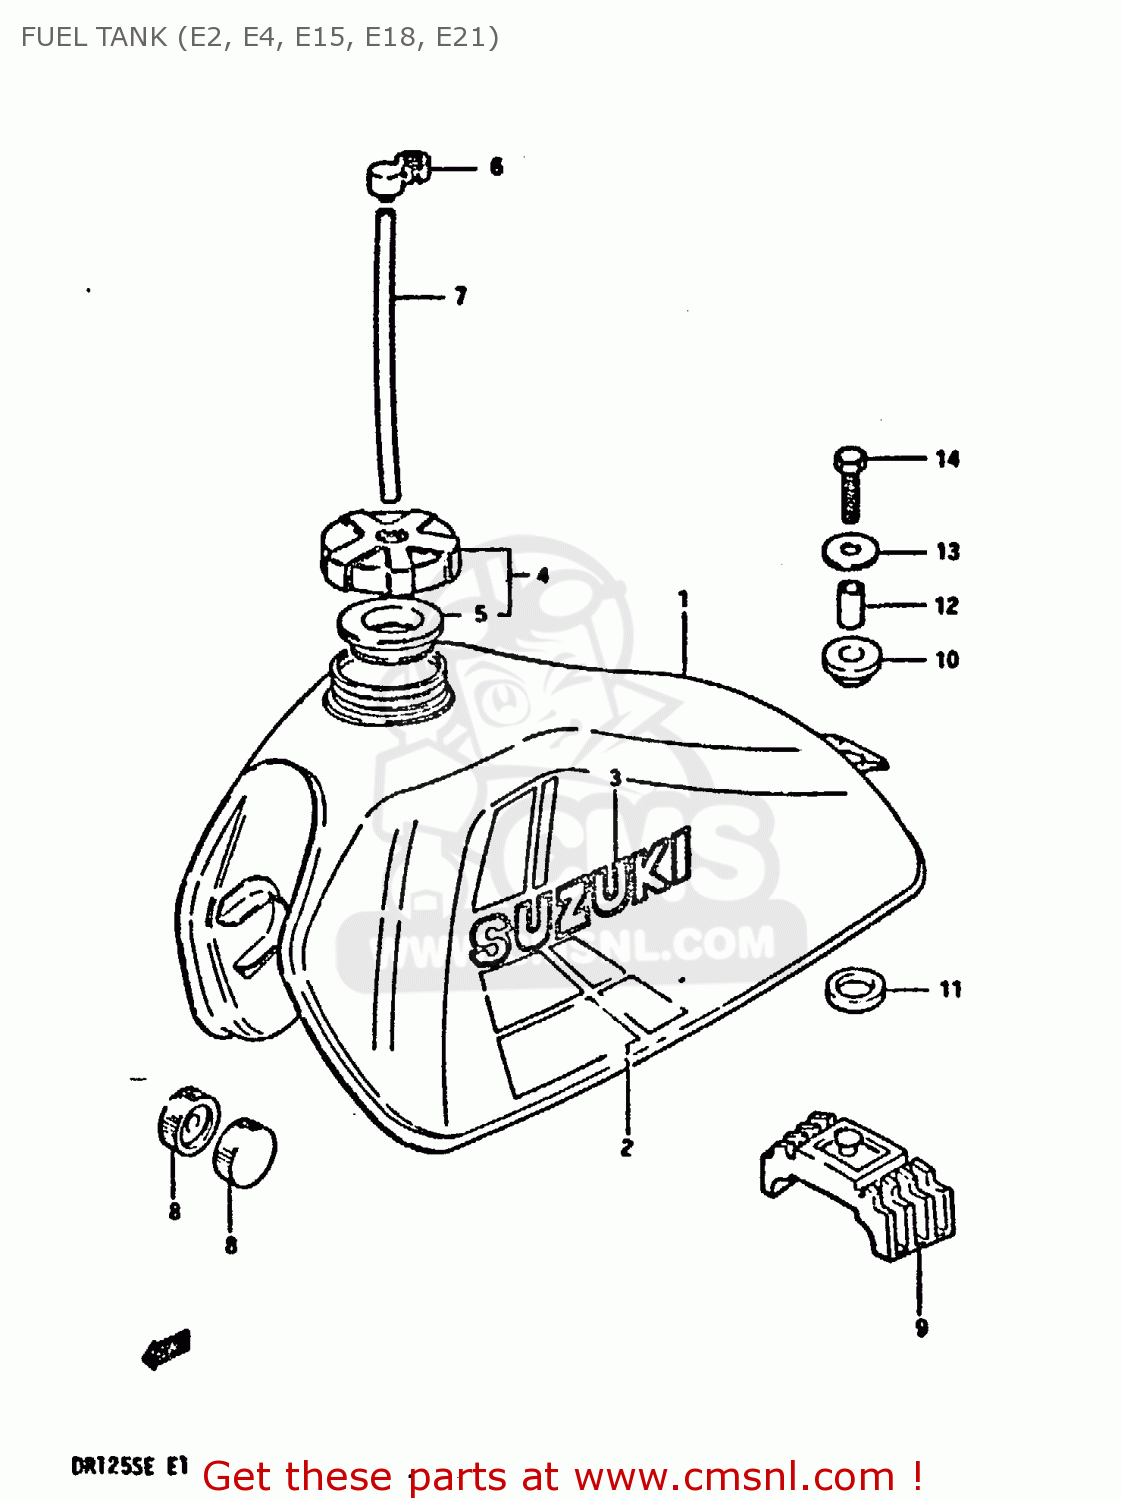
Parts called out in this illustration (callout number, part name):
1	TANK ASSEMBLY,FUEL
2	TAPE SET, FUEL TANK
3	EMBLEM
4	CAP SET,FUEL TANK
5	GASKET (NAS)
6	CLAMP,FUEL TANK BREATHER HOSE
7	HOSE
8	CUSHION
9	CUSHION,FUEL TANK
10	CUSHION
11	CUSHION
12	SPACER(8.5X12X19)
13	WASHER (8.5X29X1.6)
14	BOLT
